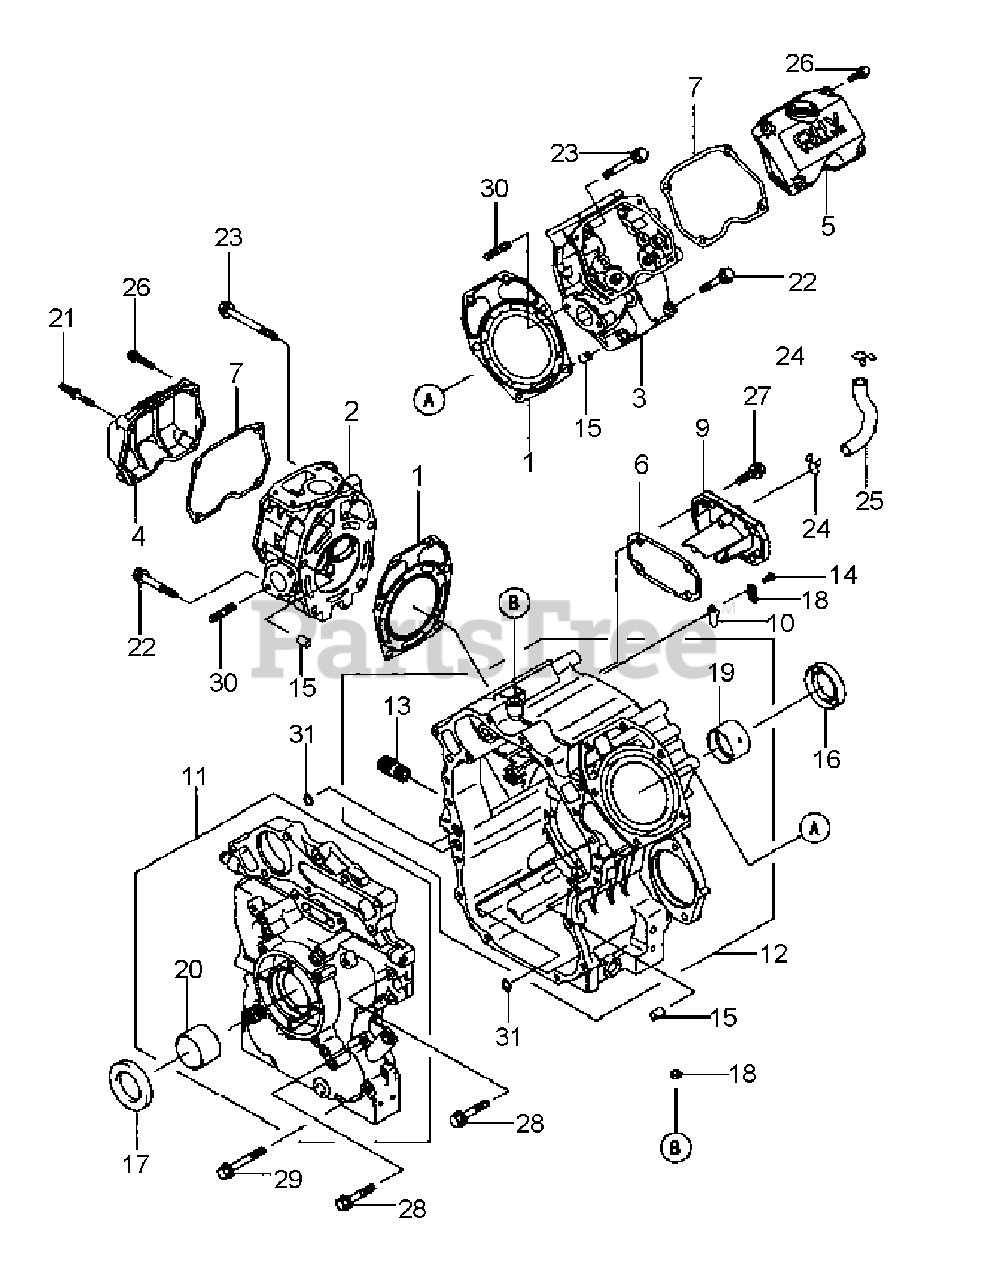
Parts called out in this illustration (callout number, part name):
2	HEAD-COMP-CYLINDER, #2
3	HEAD-COMP-CYLINDER, #1
6	GASKET, BREATHER
7	GASKET, ROCKER CASE
9	BREATHER COVER
10	BREATHER VALVE
11	COVER-CRANKCASE
12	CRANKCASE-COMP
16	SEAL-OIL,SD 38X58X11 AE
17	SEAL-OIL, SD 42X65X9 AE
18	SEAL, DS 8x12x3
19	PLANE BEARING
20	PLANE BEARING
22	BOLT 8x60
23	BOLT 8x85
26	BOLT-FLANGED
27	BOLT-FLANGED
28	BOLT-FLANGED
29	BOLT-FLANGED
30	BOLT-STUD
31	O-RING 11mm
